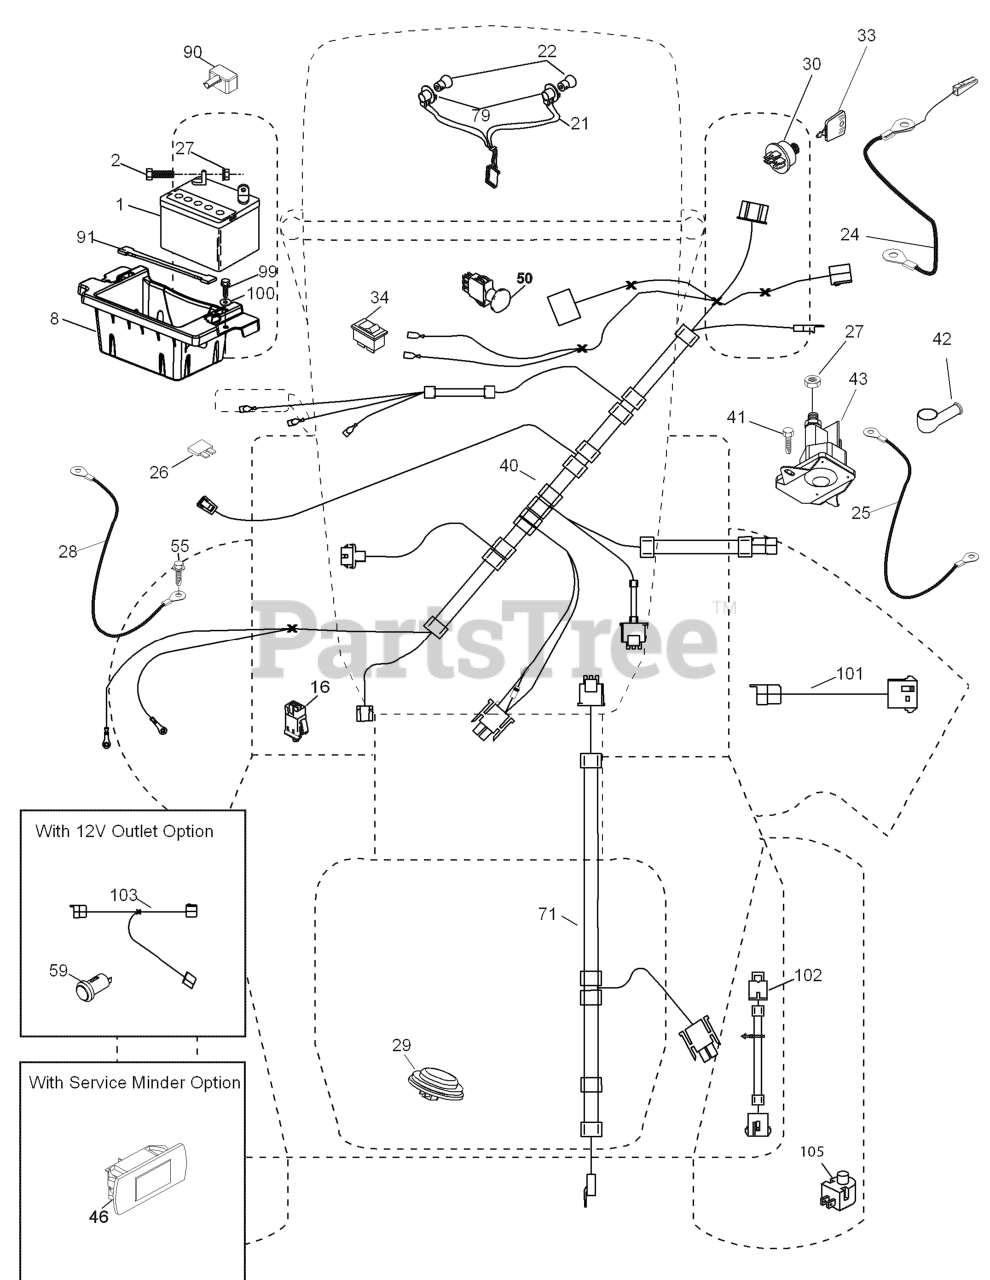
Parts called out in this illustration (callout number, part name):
1	Battery
2	BOLT.HEX.1/4.X.3/4.DICHROMATE
8	BOX.BATTERY.MOUNT.FRONT.LT
16	SWITCH INTERLOOK PUSH-IN
21	HARNESS ASSY LIGHT
24	CABLE.BATT.POS.WIRE.TG.DA SOL
25	CABLE.STARTER.6G.BL/RED.17.5
26	FUSE 20AMP
27	NUT
28	CABLE GROUND 6 GA 21" 90T BLK
29	SWITCH.SEAT.DELTA.OPC.
30	SWITCH.IGN.DELTA.W.LGH.ROS
33	KEY.CHAIN.BLISTER.PACK.GEN.INT
40	HARNESS.IGN.DASH.HUQ/P
41	SCREW
42	TERMINAL COVER
43	SOLENOID.W/BRASS.PLUNGER
46	RP.GUAGE.SRVCMNDR.HRMTR.
50	RP.PTO.SWITCH.8 TERMINAL.BLACK
55	SCREW 5/16"
59	OUTLET.12-VOLT
71	HARNESS-CHASSIS SUB
79	BULB HOLDER ASM.
81	RELAY HARNESS.SEALED
90	COVER.TERMINAL.BATTERY
91	STRAP.BATTERY.MOUNT.FRONT(2 2)
99	SCREW HEXWSHR 1/4-20X3/4
100	WASHER
101	PIGTAIL.MATNLK.NEW.HAR
102	HARNESS PIGTAIL PCH TEX ROS
103	HARNESS PIGTAIL 12V OUTLET
105	REVERSE SWITCH
